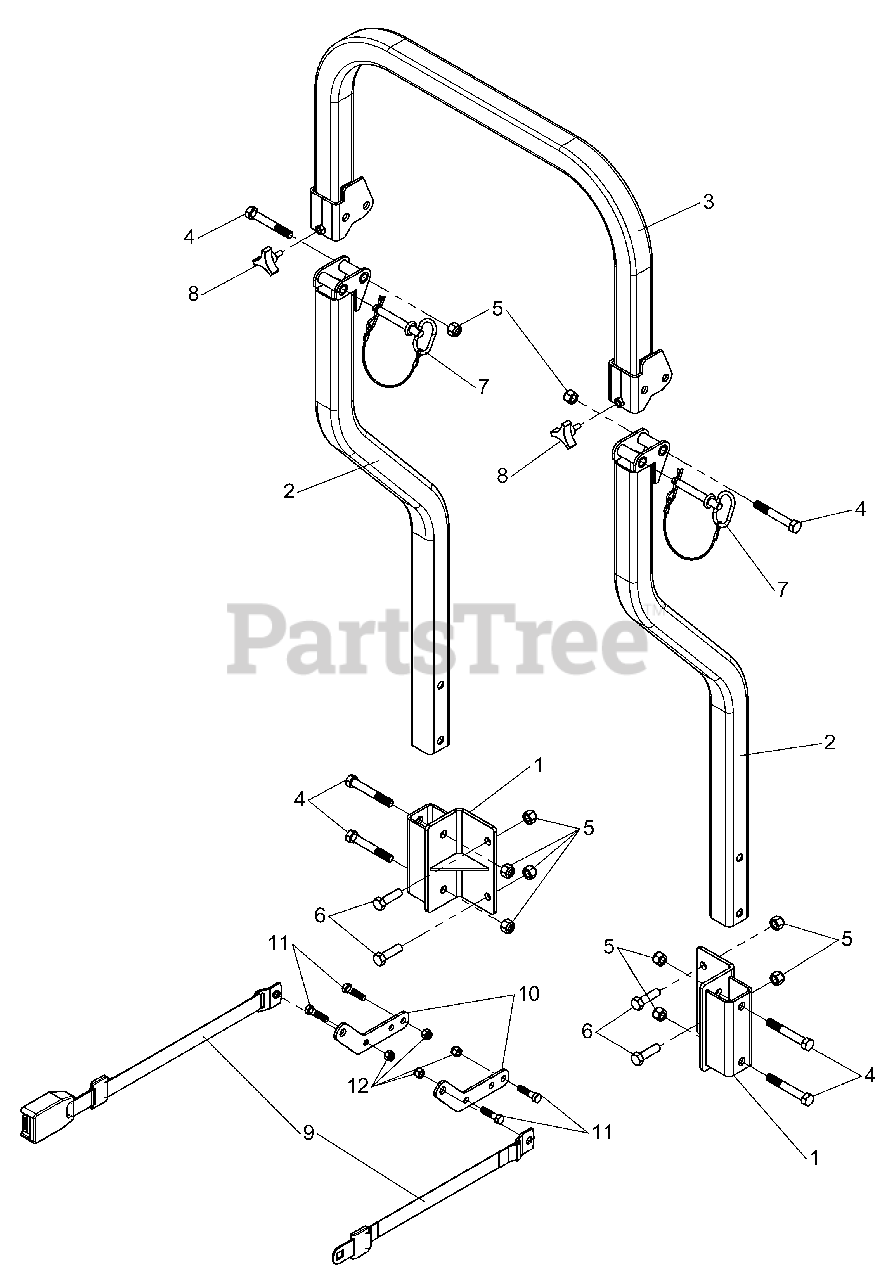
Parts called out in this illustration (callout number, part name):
1	*ROPS SOCKET
2	*ROPS POST
3	*ROPS TOP LOOP
4	CAPSCREW, Hex Hd, 1/2-13 x 3-1/2
5	NUT, 1/2-13 HEX NYLON LOCK
6	BOLT, 1/2-13 X 1-3/4 GD5 YZ
7	PIN, Hitch, .50 x 3.25 W/ Lanyard
8	KNOB, External Thread, 5/16-18
9	*SEAT BELT, COMPLETE W/ HARDWARE
10	ROPS, SEAT BELT MOUNT 1500
11	CAPSCREW, Hex Head, 3/8-16 X 1-1/2
12	NUT, Hex, Nylon Lock, 3/8-16
